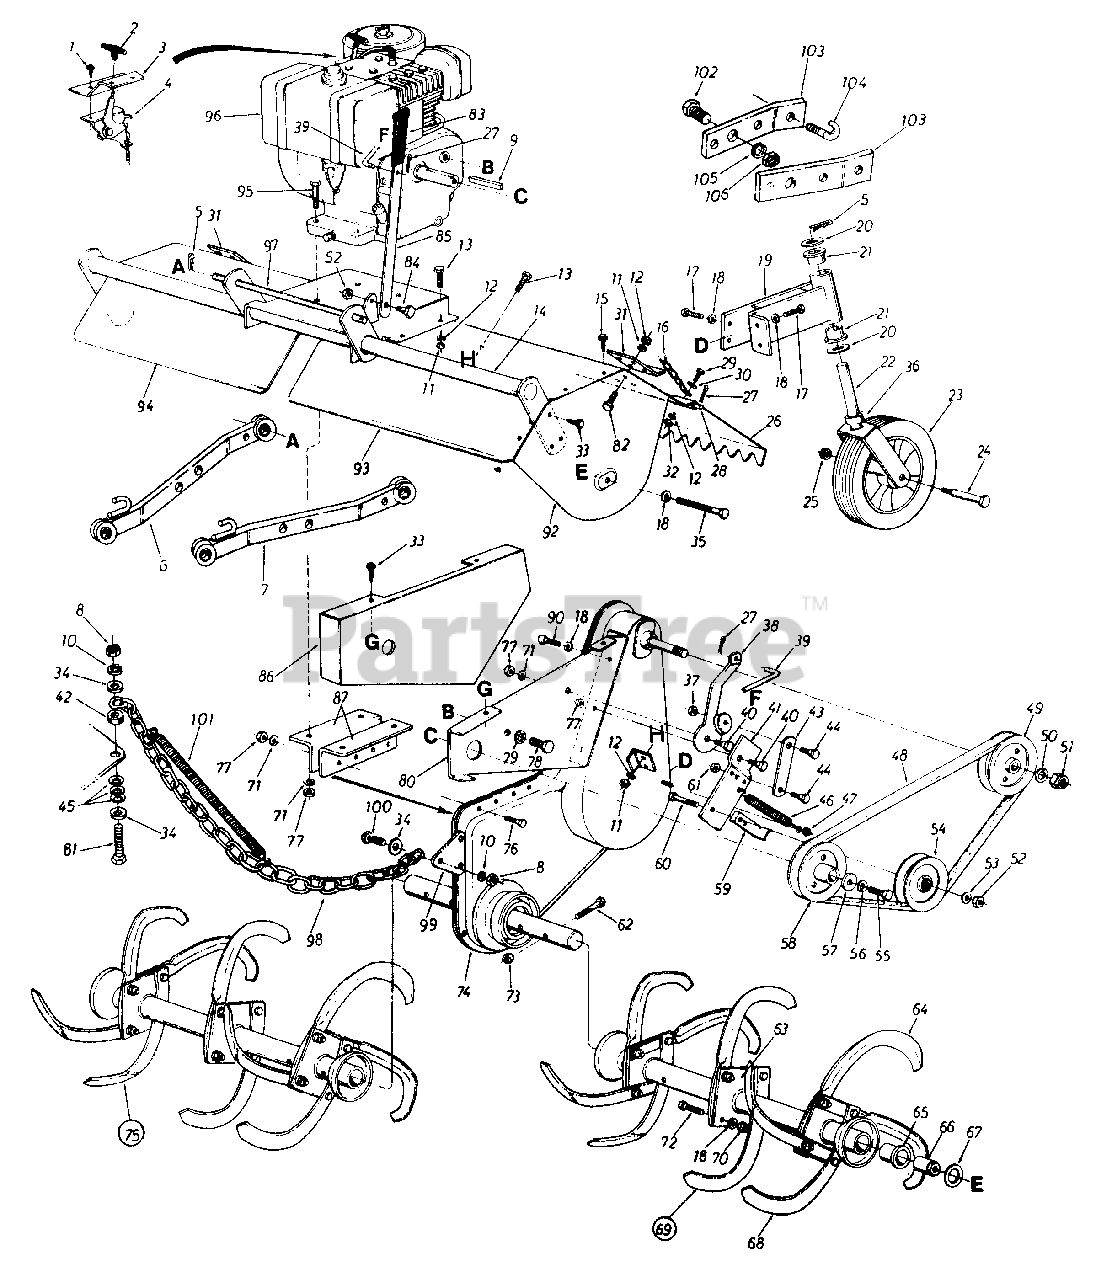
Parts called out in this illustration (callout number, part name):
1	Hex Wash. Hd. Self-Tap Scr. #8 x .50" Lg.
2	Throttle Control Knob
3	Throttle Control Bracket
4	Throttle Control Ass'y. Comp.
5	Internal Cotter Pin
6	Draft Bar Ass'y. - R.H.
7	Draft Bar Ass'y. - L.H.
8	Hex Nut 3/8-24 Thd.
9	Sq. Key 1/4" x 1/4" x 2.00" Lg.
10	L-Wash. 3/8" I.D.
11	Hex Nut 1/4-28 Thd.
12	L-Wash. 1/4" I.D.
13	Hex Bolt 1/4-28 x .62" Lg.
16	#2 Dog Chain x 20" Lg.
17	Hex Wash. Hd. Self-Tap Scr. 3/8-24 x .75" Lg.
18	L-Wash. 3/8" I.D.
19	Swivel Wheel Support
20	Fl-Wash. 3/4" I.D. x 1.50" O.D.
21	Flange Bearing 3/4" I.D. x 1.00" O.D.
22	Swivel Wheel Caster
23	Wheel Assembly 10.0 x 2.75
24	Shoulder Bolt .623" I.D. x 3.62" Lg.
25	Hex Cent. L-Nut 7/16-14 Thd.
28	L.H. Flap Rod
28	R.H. Flap Rod
29	Hex Bolt 1/4-20 x .62" Lg.
30	Fl-Wash. 1/4" I.D.
33	Hex Wash. Hd. Self-Tap Scr. 1/4" x .62" Lg.
34	Fl-Wash. .385" I.D. x 1.0" O.D. x .135 Thk.
35	Hex Bolt 3/8-16 x 1.25" Lg.
36	Spacer .752" I.D. x 1.25" O.D.
37	Hex Cent. L-Nut 5/16-18 Thd.
40	Shoulder Bolt 7/16" Dia. x 1.75" Lg.
45	Fl-Wash. .406" I.D. x .74" O.D. x .063 Thk.
46	Extension Spring .62" O.D. x 6.12" Lg.
47	Hex Crown Nut 3/8-24 Thd.
48	V-Belt 1/2" x 43" Lg. (Kevlar)
49	1/2" "V"-Pulley 4.75" O.D. x .625" Bore
50	L-Wash. 5/8" I.D.
51	Hex Ins. L-Nut 5/8-18 Thd.
52	Hex Cent. L-Nut 3/8-16 Thd.
53	Fl-Wash. 3/8" I.D.
54	Idler Pulley 4.0" O.D.
55	Hex Bolt
56	L-Wash. 7/16" I.D.
57	Fl-Wash. 7/16" I.D. x 1.38" O.D.
58	1/2" "V"-Pulley .475" O.D. x 1.00" Bore
61	Hex Cent. L-Nut 5/16-18 Thd.
62	Hex Bolt 7/16-14 x 2.00" Lg.
65	Flange Bearing 1.00" I.D.
66	Spacer
67	Thrust Wash. 1/2" I.D. x 1.55" O.D.
68	Tine - R.H.
69	Tine Assembly Comp. - L.H.
70	Hex Nut 3/8-24 Thd.
71	L-Wash. 5/16" I.D.
72	Hex Bolt 3/8-24 x 1.5" Lg.
73	Hex Cent. L-Nut 7/16-14 Thd.
77	Hex Nut 5/16-18 Thd.
78	Hex Bolt 1/2-20 x .88" Lg. (Grade 5)
79	L-Wash. 1/2" I.D.
80	Clutch Support Bracket
81	Hex Bolt 3/8-24 x 1.75" Lg.
82	Hex Bolt 1/4-28 x .75" Lg.
83	Plastic Grip
84	Shoulder Bolt .498 Dia. x .212 Lg.
85	Clutch Handle
86	Clutch Support Shroud
87	Engine Mounting Bracket
90	Hex Bolt 3/8-16 x .62" Lg
92	L.H. - Side Plate
96	8 H.P. Engine
97	Tiller Mounting Shaft 16" Lg.
98	Chain 23" Lg.
99	Tiller Mounting Bracket
100	Hex Bolt 3/8-24 x 1.25" Lg.
101	Extension Spring
102	Hex Bolt 5/8-18 x 1.62" Special
103	Drag Link Extension
104	Hitch Chain Hook
105	L-Wash. 5/8" I.D.
106	Hex Jam Nut 5/8-18 Thd.
